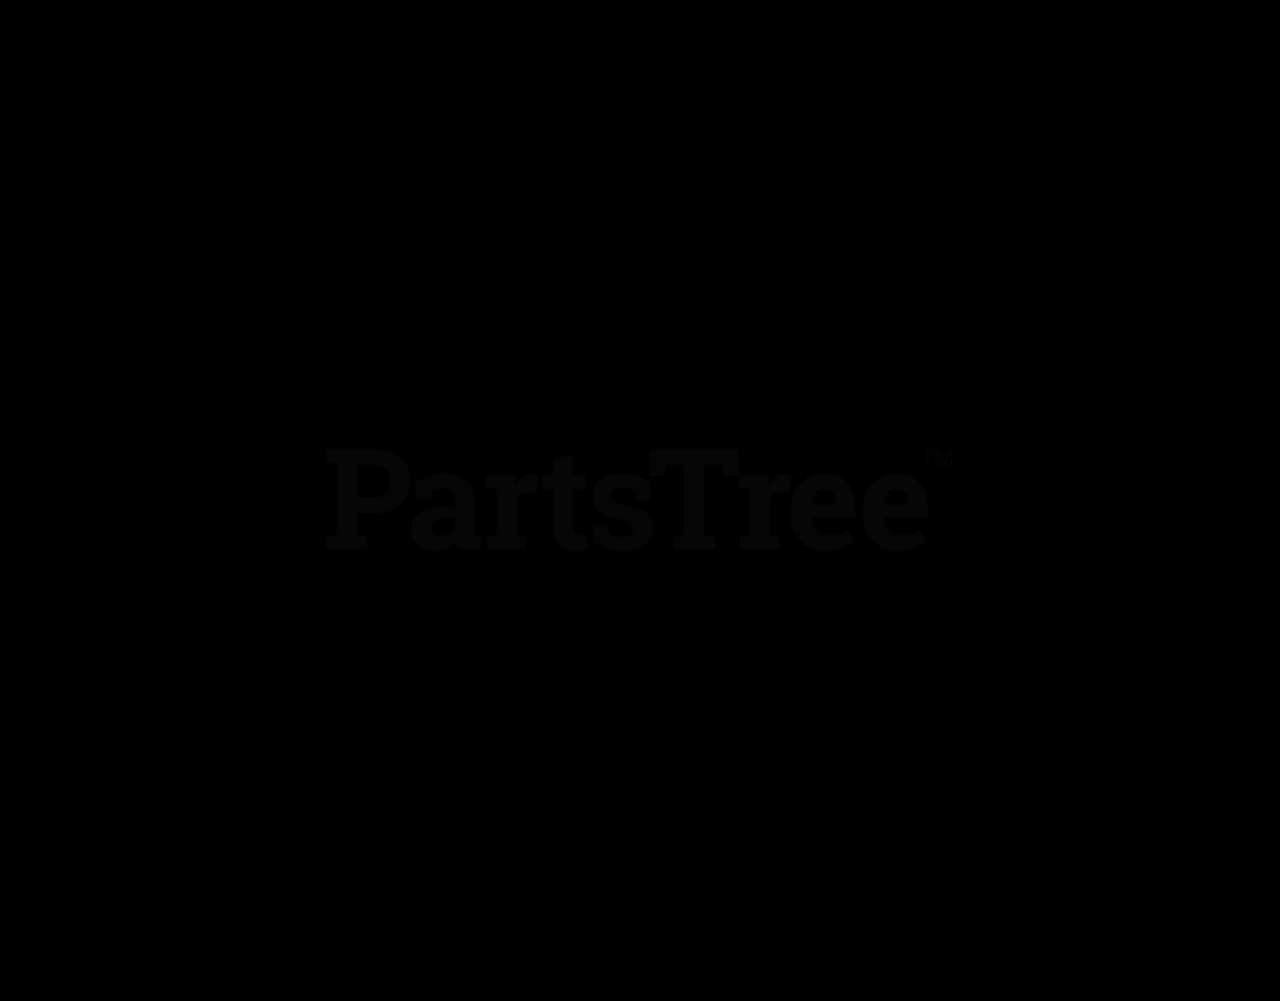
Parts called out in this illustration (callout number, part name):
1	ENGINE 4.2LG3(FWD)
2	SCREW HHCM6-1.0X16C8.8
3	WASHER LOCK M6-1/4
4	WASHER FLAT 1/4-M6 ZINC
5	COVER IAC ACTUATOR
6	SHIELD SPARK PLUG BOOT RH
7	RIVET POP .125X.275SS
8	WASHER FLAT 5/16-M8 ZINC
9	WASHER LOCK M8-5/16
10	SHIELD SPARK PLUG BOOT LH
11	CAP ANTIFREEZE 5/8"ID X 2.5"LG
12	CLAMP HOSE BAND 1.0"
13	NUT HEX M12-1.75 G8YELCHR
14	WASHER LOCK M12
15	WASHER FLAT M12
16	RESTRICTOR COOLANT BYPASS
17	HOSE COOLANT BYPASS 4.2L
18	SWITCH HI-TEMP 245D X 3/8NPT
19	GASKET THERMOSTAT 4.2L
20	WASHER LOCK M5
21	SCREW HHTT M5-0.8X10BP
22	THERMOSTAT 192 DEGREE
23	THERMOSTAT HOUSING
24	SCREW HHCM6-1.0X 60 C8.8
25	CLAMP HOSE #28 1.32-2.25
26	HOSE RADIATOR REAR
27	STARTER MOTOR 12V
28	SCREW HHC M12-1.75 X 30 C8.8
29	SCREW HHCM12-1.75X 60 C10.9
30	SCREW HHC M12-1.75 X 40 C8.8
31	FLEX PLATE G3
32	WASHER FLAT .45X1.00
33	WASHER LOCK M10
34	SCREW HHCM10-1.0X30 C10.9
35	SCREW HHC M12-1.75X 90 C10.9
36	SCREW HHCM10-1.5X35 C8.8
37	WASHER FLAT 3/8-M10 ZINC
38	ENGINE ADAPTER 4.2L MACHINED
39	SPACER FLEXPLATE 4.2L
40	SCREW HHCM10-1.5X20 C8.8
41	HEAT SHIELD EXH 4.2L LH
42	CAP TUBE M22-1.5 STEEL
43	NUT HEX M10-1.5 G8 YEL CHR
44	PLUG EXPANSION 14 OD
45	CLAMP VINYL 1.5 X .281 Z
46	SCREW HHC M6-1.0 X 25 LONG
47	TUBE UPPER COOLANT
48	SCREW HHC M5-0.8X 20 G8.8
49	IGNITION COIL ASSY
50	SCREW HHC M5-0.8X 12 C8.8
52	BRACKET IGNITION COILS G3 4.2L
53	VALVE PCV G3
54	DECAL REFER TO OWNERS MANUAL
55	SCREW SHC M8-1.25 X 30 G12.9
56	WELDMENT IDLER BRACKET 4.2L
57	PULLEY GROOVED ENGINE IDLER
58	BOLT HEX FL HD M8-1.25X 28
59	CAP ANTIFREEZE RUBBER 8.5DIA
60	CLAMP HOSE BAND .75
61	STRAP INTAKE ACTUATOR
62	CAP ANTIFREEZE 5/8"IDX 1.2"LG
63	BRACKET DC ALTERNATOR LH 4.2L
64	ALTERNATOR DC W/OUT PULLEY
65	SPACER ALTERNATOR 4.2L G3
66	CLAMP HOSE BAND .50
67	CAP VINYL 3/8"IDX1"DP BLK
68	SWITCH OIL PRESSURE 10PSI 2P
69	SCREW HHC M8-1.25X 25 C8.8
70	SPACER DC ALTERNATOR PULLEY
71	PULLEY 117 OD DC ALTERNATOR
72	SCREW HHC M10-1.5X 160 C8.8
73	SCREW HHC M8-1.25X 115 LONG
74	SCREW HHC M8-1.25X 105 LONG
75	TUBE COOLANT LOWER RADIATOR
76	O-RING 1-1/2" X 1 -3/4" X 1/8"
77	PULLEY WATER PUMP 4.2L
78	SCREW HHC M6-1.0X12G8.8
79	SPACER 46.5 O.D. X 15 I.D. X 5 THK.
81	BELT SERPENTINE 71.04"
82	HARMONIC BALANCER REWORK 4.2L
83	WASHER FLAT M5
84	SCREW HHC M5-0.8X 10 C8.8
85	BRACKET DC ALTERNATOR RH 4.2L
86	WASHER NYLON .50 X .87 X .06
87	ADAPTER M12-1.75 X 3/8NPT
88	BARBED STR3/8NPTX 3/8
89	CLAMP HOSE .38-.87
90	HOSE OIL DRAIN ASSY 21"
91	SCREW HHC M6-1.0X12SS
92	WASHER LOCK 1/4-M6SS
93	WASHER FLAT 1/4 SS
94	HEAT SHIELD EXH 4.2LRH
95	CAP VINYL .5"IDX1.0"DP BLK
96	CLAMP HOSE BAND .63
97	ADAPTER THERMOSTAT
98	HOSE COOL 5/8"ID 250#WP (24" LG)
99	BSHG RDCR HEX 1/4 TO 1/8
100	TUBE ASSY EGR OUTLET REWORK
101	SCREW HHC M6-1.0X 15 LONG
102	BOLT STRIP 3/8-16X1-1/4
103	SPRING COMPRESSION .711 X 1.00
104	PRESSURE RELIEF VALVE
106	SPARK PLUG WIRE SET 4.2L
107	RETAINER SPARK PLUG WIRE - LOOSE TYPE
108	RETAINER SPARK PLUG WIRE - ATTACHED TYPE
109	CLAMP HOSE#10.56-1.06
110	HARN LOW OIL PRESSURE SWITCH
111	ASSY MAGPICKUP(3/8-24 MALE)
